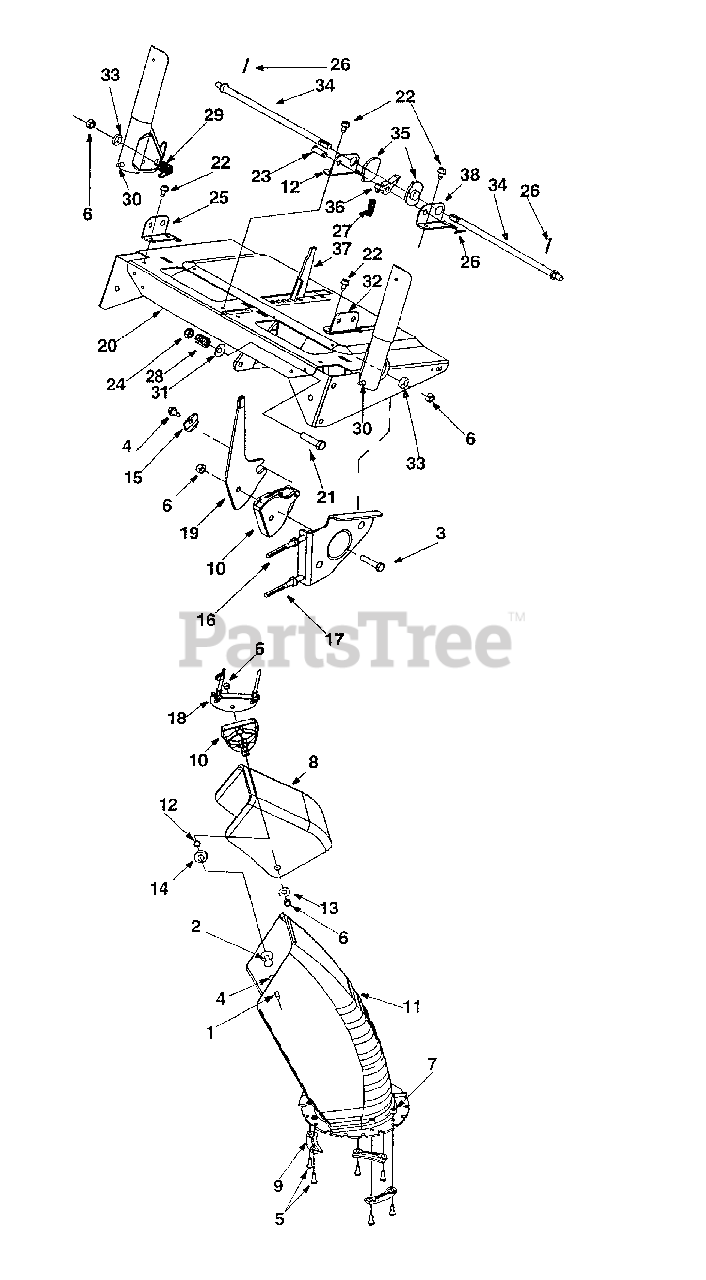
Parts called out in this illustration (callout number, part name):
1	Carriage Screw
2	Carriage Bolt 5/16-18 x 1.75"
3	Hex Bolt 5/16-18 x 1.5"
4	Hex AB Screw 1/4-14 x .625"
5	Hex Screw 1/4-20 x .75"
6	Hex Lock Nut
7	Hex Flange Lock Nut
8	Upper Chute
9	Chute Flange Keeper
10	Cable Guide: Chute Tilt
11	Lower Chute
13	5/16 Washer
14	Flat Washer
15	Special Washer
16	Chute Control Cable
17	Chute Cable w/Clip
21	Hex Bolt 3/8-24 x 1.5"
22	TT Screw 1/4-20 x 0.5"
23	Clevis Pin
26	Cotter Pin
29	Torsion Spring
30	Rubber Bumper
31	Bell Washer
33	Special Washer
35	Cam: Handle Lock
36	Pawl: Handle Lock
